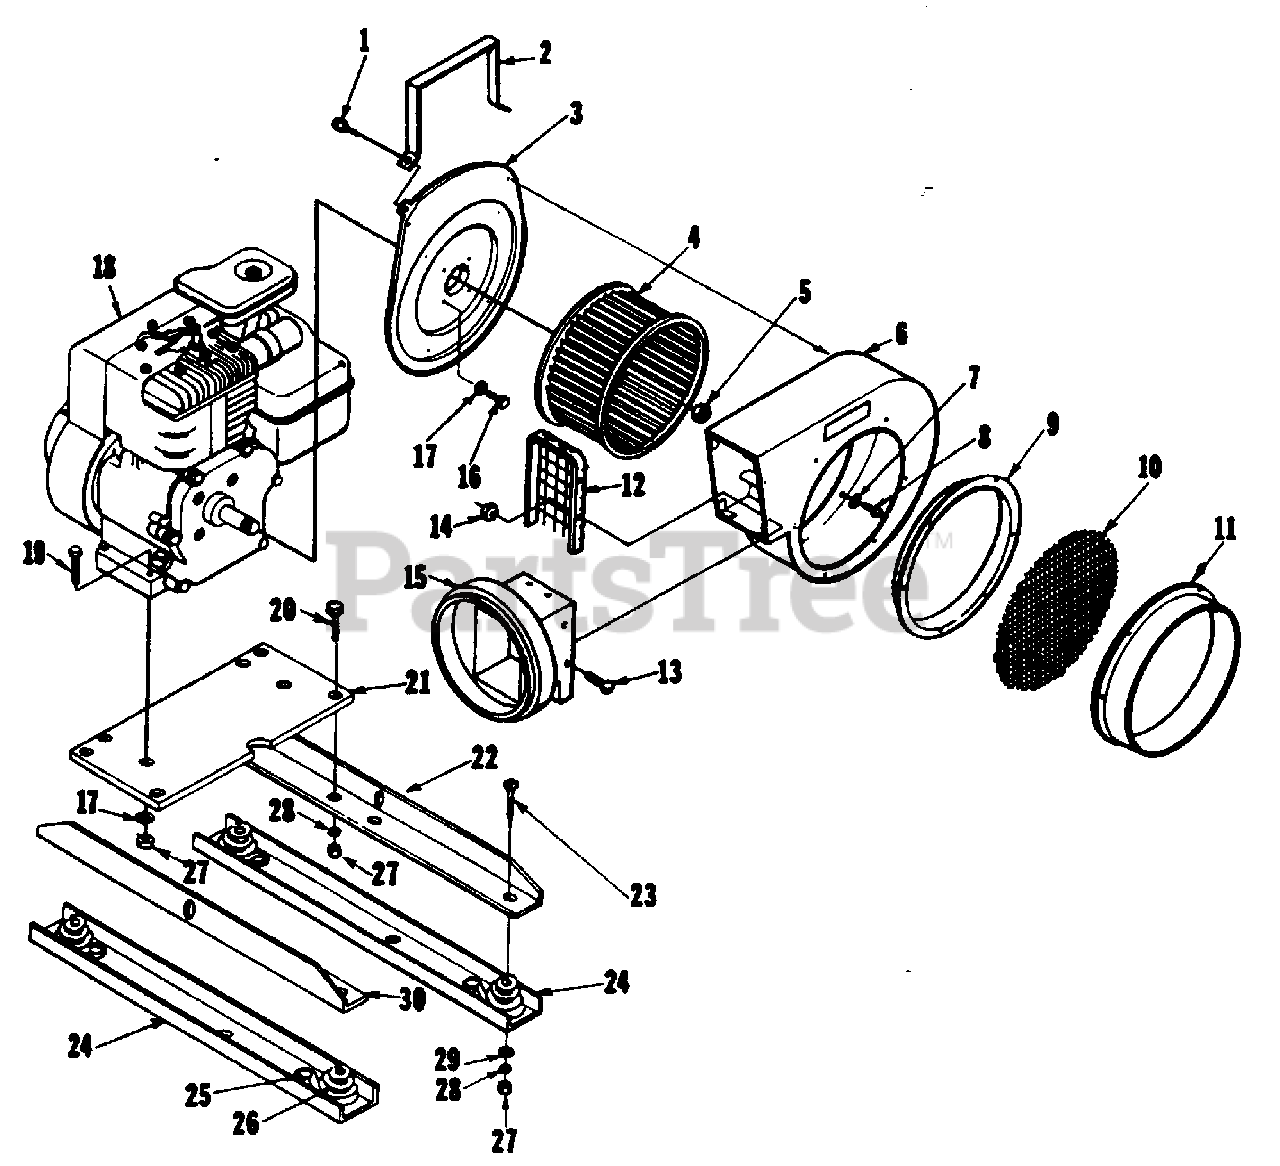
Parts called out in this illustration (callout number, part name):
1	SCREW- Hex hd. 1/4-20 x 1/2
2	HANDLE- Carrying
3	PLATE- Blower mounting
4	ROTOR- Blower
5	NUT- Elastic stop, 5/8-18 (111B-1 only)
6	HOUSING- Blower
7	WASHER- Lock 1/4
8	SCREW- Hex hd., 1/4-20 x 1/2
9	VENTURI- Blower
10	SCREEN- Inlet
11	COLLAR- Inlet
12	Support & Screen (discharge)
13	SCREW- Pan hd., 10-24 x 1/2
13	SCREW- Pan hd., 10-24 x 5/8
14	NUT- Hex 10-24
15	OUTLET- Blower
16	SCREW- Hex hd., 5/16-24 x 7/8
17	WASHER- Lock 5/16
18	ENGINE- B & S
19	SCREW- Hex hd. 5/16-18 x 1 1/2
20	SCREW- Hex hd. 5/16-18 x 3/4
21	SUPPORT- Engine
22	ANGLE- Base (left side)
23	SCREW- Hex hd. 5/16-18 x 1
24	SKID ASSEMBLY
25	RIVET 1/4 x 1/2
26	SPRING
27	NUT- Hex 5/16-18
28	WASHER- Lock 5/16
29	WASHER- Flat 5/16
30	ANGLE- Base (right side)
